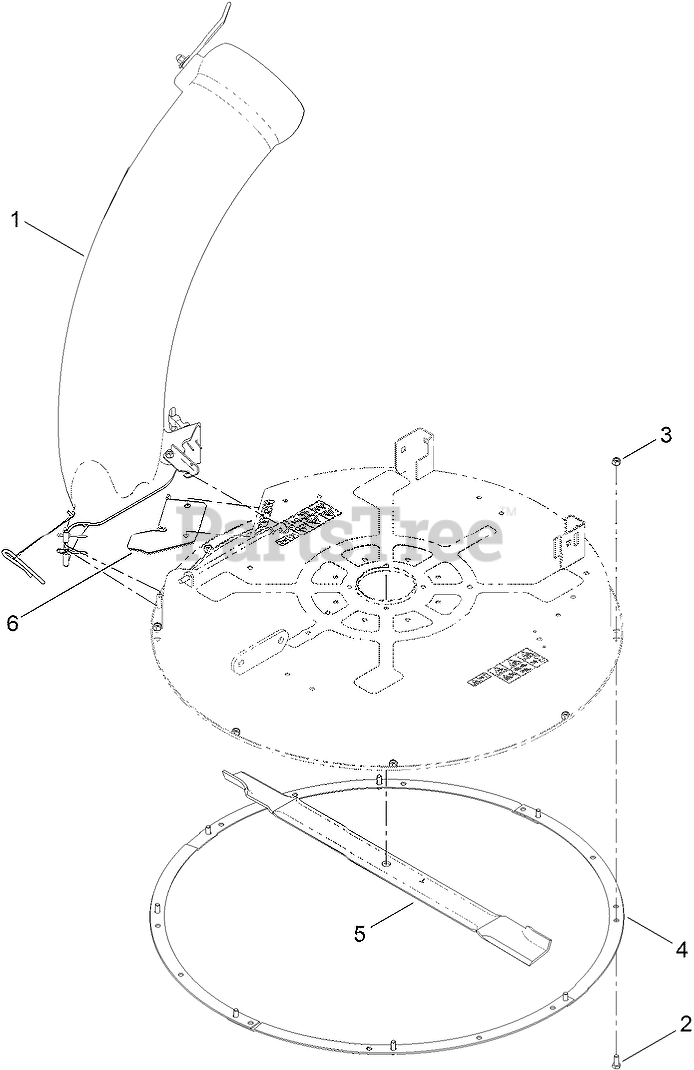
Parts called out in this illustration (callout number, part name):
1	32 INCH CHUTE ASM
2	SCREW-HH
3	NUT-LOCK, NI
4	RING-DECK
6	BRACKET-CUTOFF
